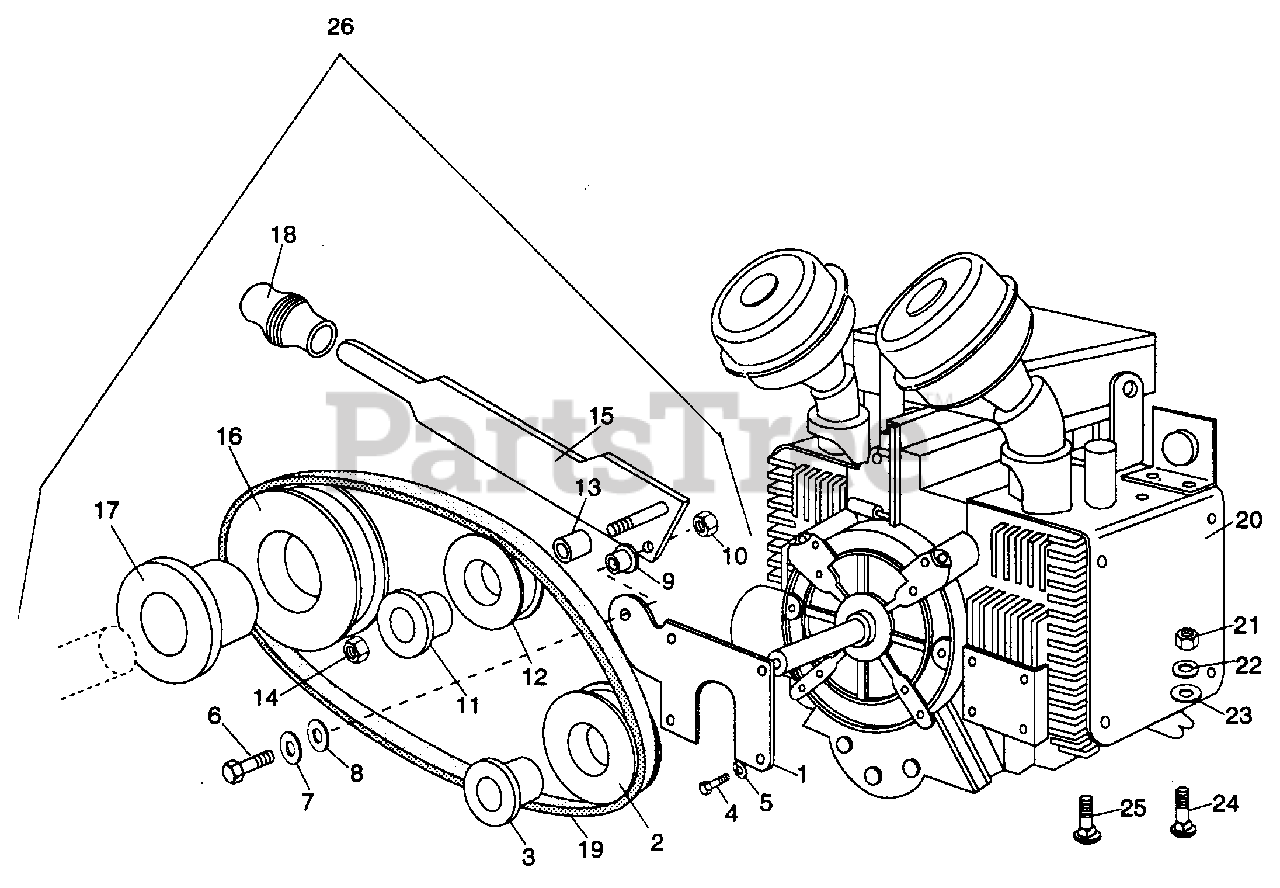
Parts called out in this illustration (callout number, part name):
1	ENGINE BRACKET WELDMENT
2	ENGINE SHEAVE 3-3V41
3	ENGINE BUSHING SH 1.12
4	BLT-HEX .44-14X1.25 PL GR 5
5	WSHR-LOCK .438X.133 HVY
6	BLT-HEX .50-13X2.00 PL GR 5
7	WSHR-FL-STL .531X1.062X.095 PL
8	WSHR .50 BRONZE(ND)
9	BSHG-FLG .500X.750X.625X.937
10	NUT-LK-CROWN .50-13 GR C PL
11	BUSHING IDP1 X 5/8
12	IDLER SHEAVE SP3V4.1
13	SPACER
14	NUT-LK-FLEX .625-11
15	CLUTCH HANDLE WELDMENT
16	FLYWHEEL SHEAVE 3-3V80
17	BUSHING, SK X 1-1/2
19	V-BELT 3/3VX500
20	ENGINE KOHLER 18 H.P. SPEC. #24653
21	NUT-HEX .375-16
22	WSHR-LOCK .375X.115 HVY PL
23	WSHR-FL-STL .438X1.0X.083 PL
24	BLT-RDHDSQNK .38-16X1.50 GR 5 PL
25	BLT-RDHDSQNK .38-16X1.25 GR 5 PL
26	IDLER CLUTCH KIT 1 1/8 IN.(INC. 1 - 19 )
